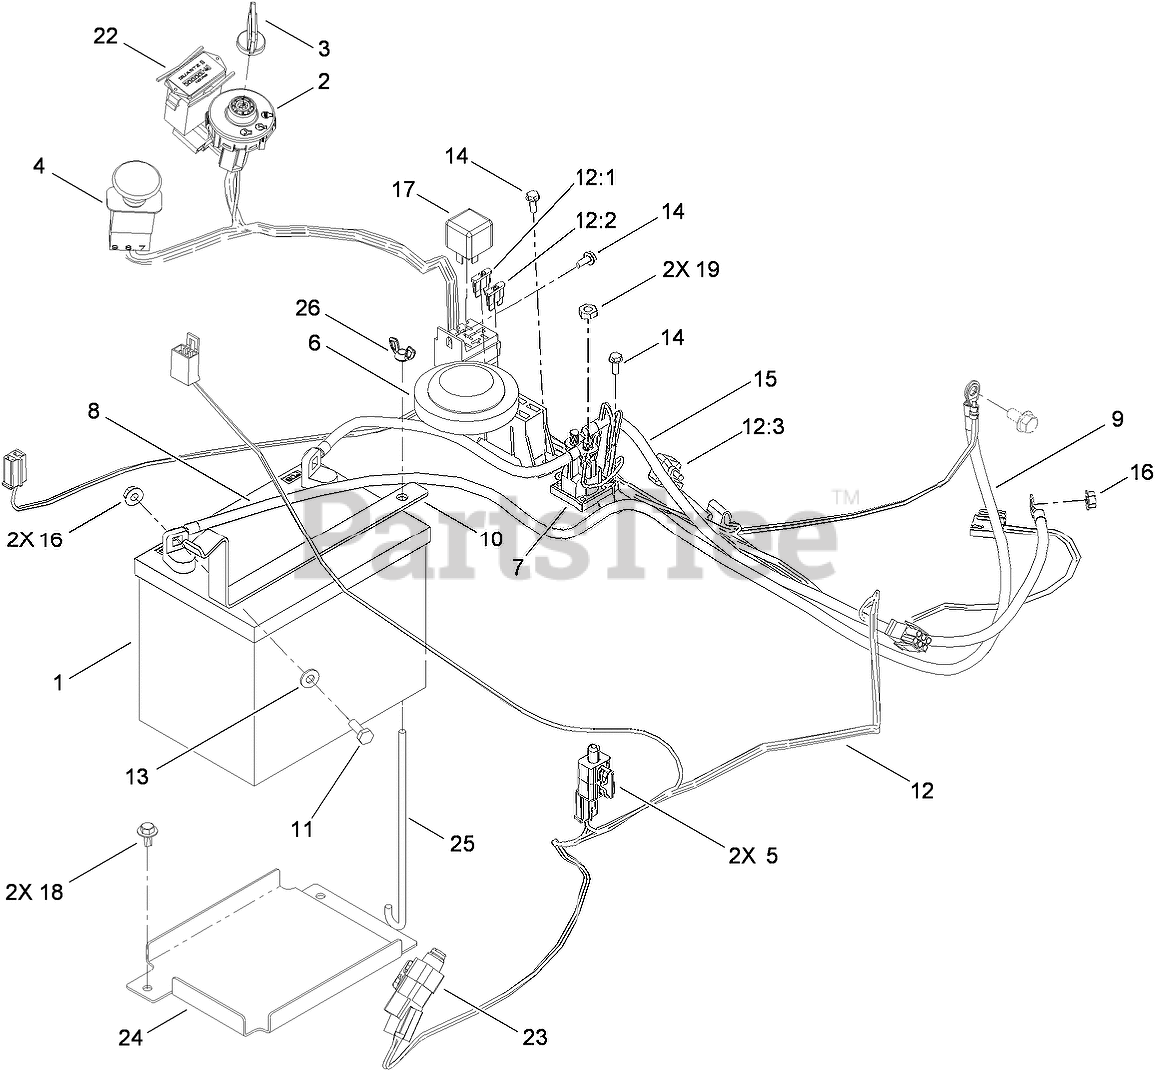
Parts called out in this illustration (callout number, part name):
1	BATTERY
2	SWITCH-IGNITION
3	KEY-IGNITION
4	SWITCH-PTO
5	SWITCH
6	SWITCH-SEAT
7	SOLENOID
8	CABLE-BATTERY, POSITIVE
9	CABLE-BATTERY, NEGATIVE
10	STRAP-BATTERY
11	SCREW-HH
12	Harness-Wire
12:1	FUSE-BLADE, 30 AMP
12:2	FUSE-BLADE, 25 AMP
13	WASHER-FLAT
14	SCREW-TAPTITE
15	WIRE-21 INCH
16	NUT-HF
17	RELAY
18	SCREW-HHFTF
19	NUT-JAM
22	METER-HOUR
23	SWITCH-PLUNGER W/COVER
24	TRAY-BATTERY
25	BOLT-HOLDDOWN
26	WINGNUT
